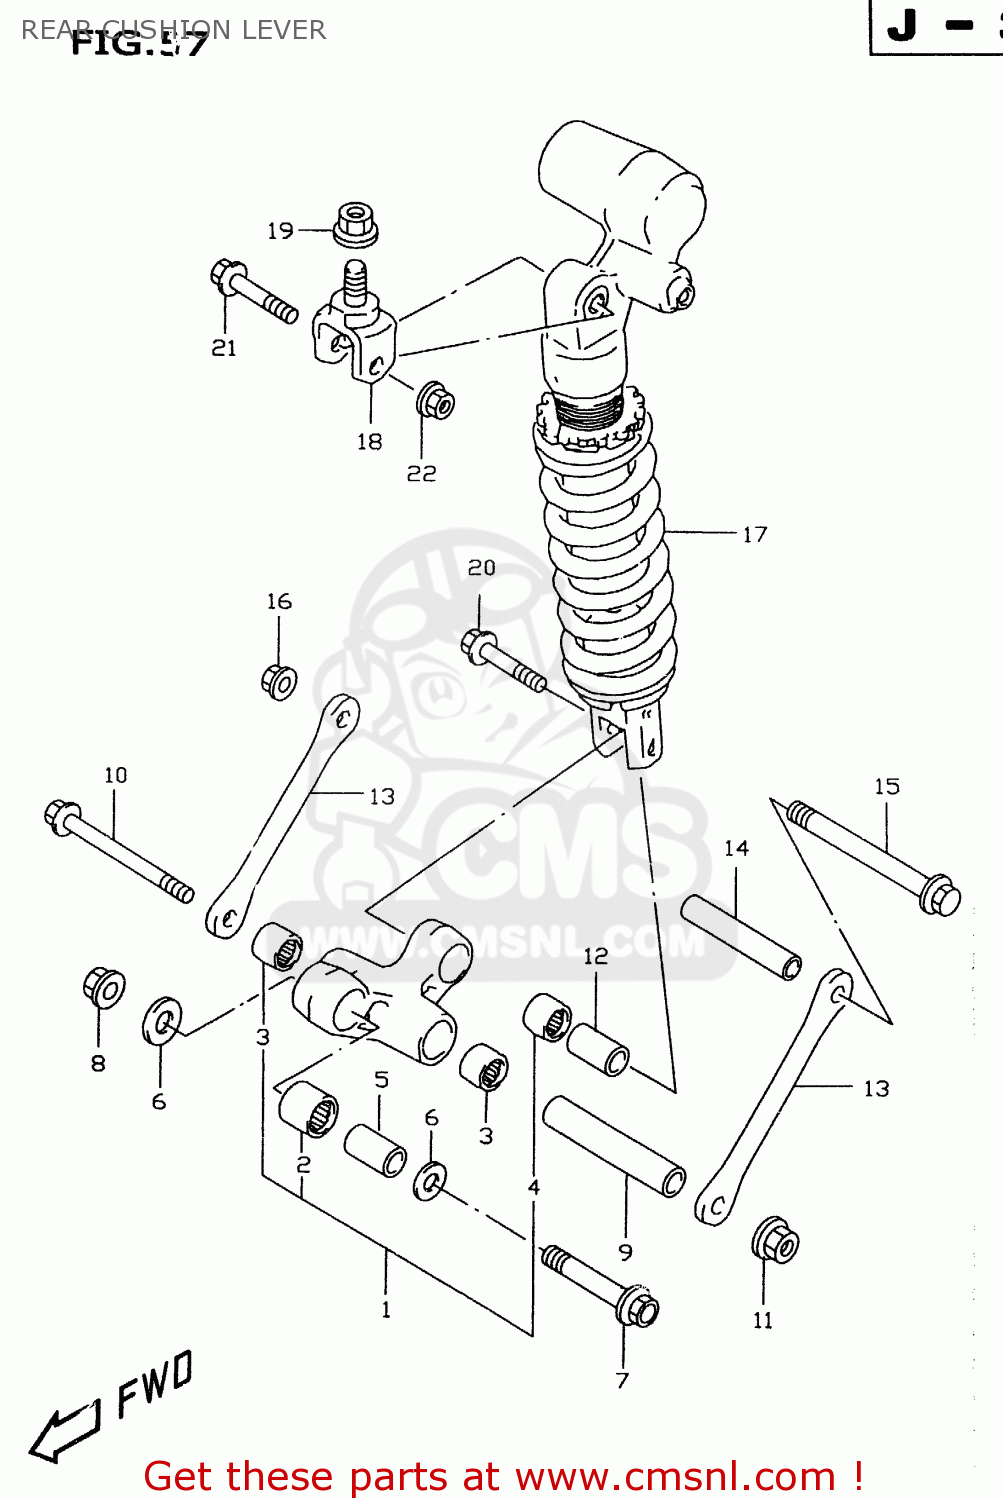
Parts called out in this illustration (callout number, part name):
1	LEVER SET,RR CUSHION
2	BEARING(20X27X30)
3	BEARING(17X24X20)
4	BEARING(17X24X26)
5	SPACER,RR CUSHION LEVER FR
6	WASHER
7	BOLT,RR CUSHION LEVER FR
8	NUT 12MM
9	SPACER,RR CUSHION LEVER CTR
10	BOLT,RR CUSHION LEVER CTR
11	NUT 12MM
12	SPACER,RR CUSHION LEVER
13	ROD,RR CUSHION LEVER
14	SPACER,RR CUSHION LEVER CTR
15	BOLT,RR CUSHION LEVER CTR
16	NUT 12MM
17	ABSORBER ASSY, REAR SHOCK
18	BRACKET,RR SHOCK ABSORBER UP
19	NUT
20	BOLT(10X44)
21	BOLT(10X54)
22	NUT
